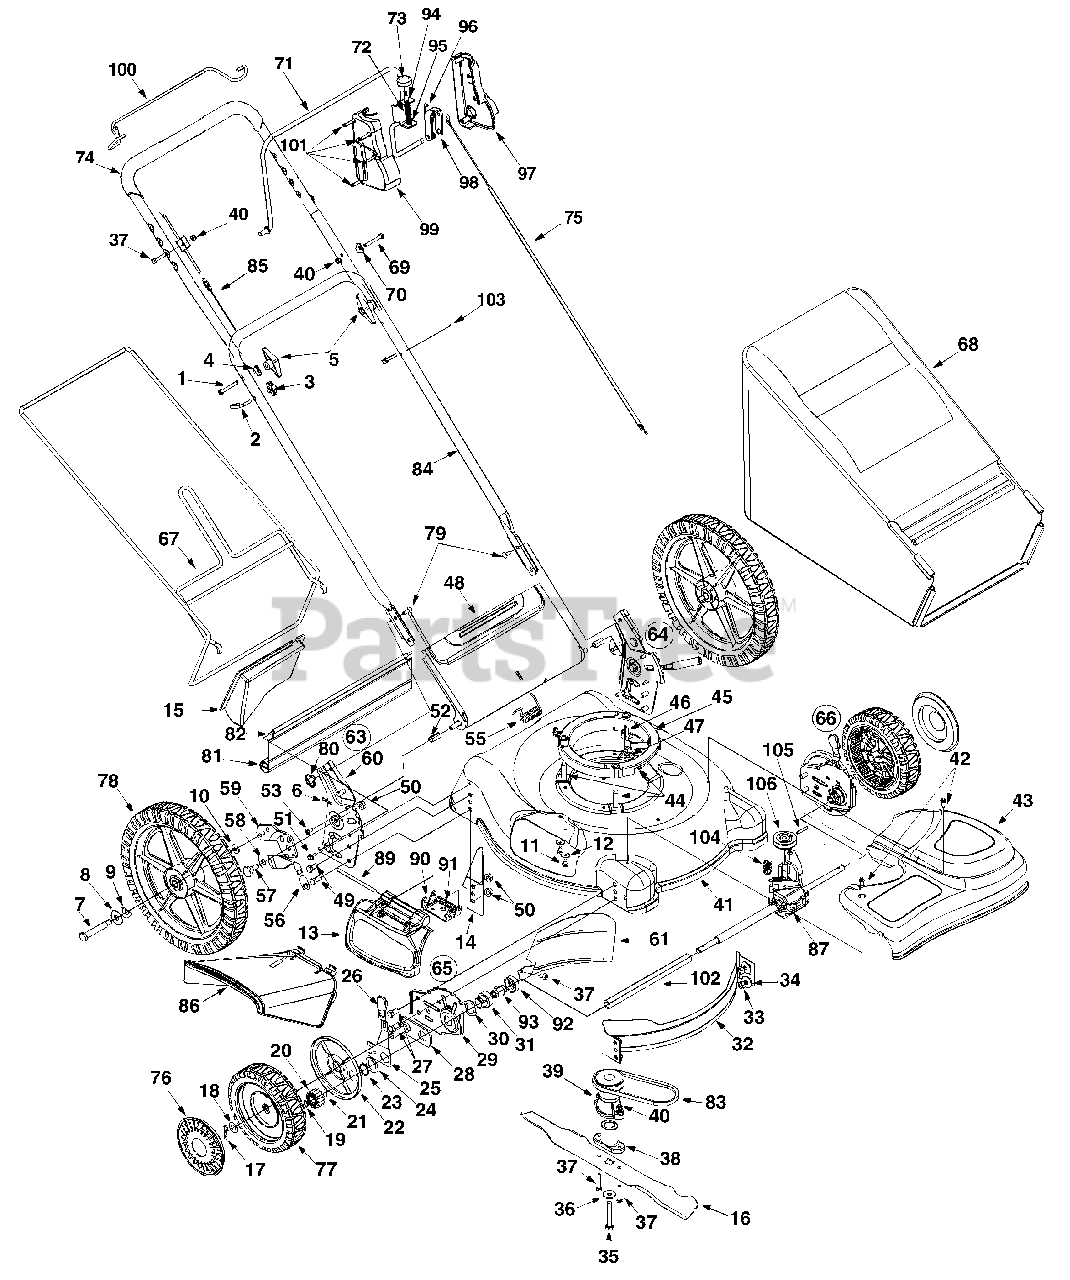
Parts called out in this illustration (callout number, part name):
1	Carriage Bolt
2	Rope Guide
4	Saddle Washer
5	Handle Knob
6	Hairpin Clip
7	Shoulder Screw
8	Flat Washer .510 I.D. x 1.373 O.D.
9	Spring Wash. .500 I.D. x 1.00 O.D.
10	Bell Washer .375 I.D. x .870 O.D.
11	Tapp Screw 1/4-20 x .500
12	Bell Wash. .265 I.D. x .75 O.D.
13	Mulching Plug (Hinged)
15	Mulching Plug
16	Mulching Blade w/Star
16	Standard Blade
17	Hairpin Clip
18	Flat Washer
19	Snap Ring
20	Gear 14T RH
20	Gear 14T LH
21	Dowel Pin
22	Wheel Dust Cap
23	Snap Ring
24	Washer DD 1.5" O.D.
25	Front Lever RH
25	Front Lever LH
26	Knob
27	Hex Screw
28	Pivot Plate Assembly
30	Wave Washer
31	Bearing Support
34	Bell Washer
36	Bell Washer
37	Hex Screw 1/4-20 x 1.5"
38	Blade Adapter
39	Drive Pulley
40	Hex Lock Nut
43	Transmission Cover
45	Engine Spacer Assembly
46	Belt Keeper Pin
47	Hex Nut 1/4-20
50	Flange L-Nut 3/8-16
51	AB Tap Screw 1/4-14 x .625"
53	Pan Hd. Screw 1/4-20 x .5"
54	Pivot Rod
55	Torsion Spring
56	Foam Grip
57	Shoulder Screw
58	Spring Lever
59	Pivot Bar LH
59	Pivot Bar RH
60	Handle Bracket Assembly RH
60	Handle Bracket Assembly LH
62	Scr. AB 1/4-14 x 0.625"
65	Height Adjuster Ass'y Comp. RH
66	Height Adjuster Ass'y Comp. LH
68	Grass Bag w/Half Sail
69	Hex Hd. Cap Screw
70	Saddle Washer
72	Compression Spring
76	Hub Cap
77	Wheel 8 x 2
78	Wheel 14 x 2
79	Carriage Bolt
80	Wing Nut
81	Trail Shield
82	Wire
83	V-Belt
85	Drive Cable
86	Chute Deflector
87	Transmission Assembly Comp.
89	Hinge Pin
91	Torsion Spring
92	Bearing Retainer
93	Bearing Sleeve .50 I.D.
95	Retention Spring
96	Torsion Spring
97	Control Cover LH
99	Control Cover RH
101	Hi-Low Screw
102	Sleeve Spacer LH
102	Sleeve Spacer RH
103	Cable Tie
104	Belt Tension Spring
106	Input Pulley
